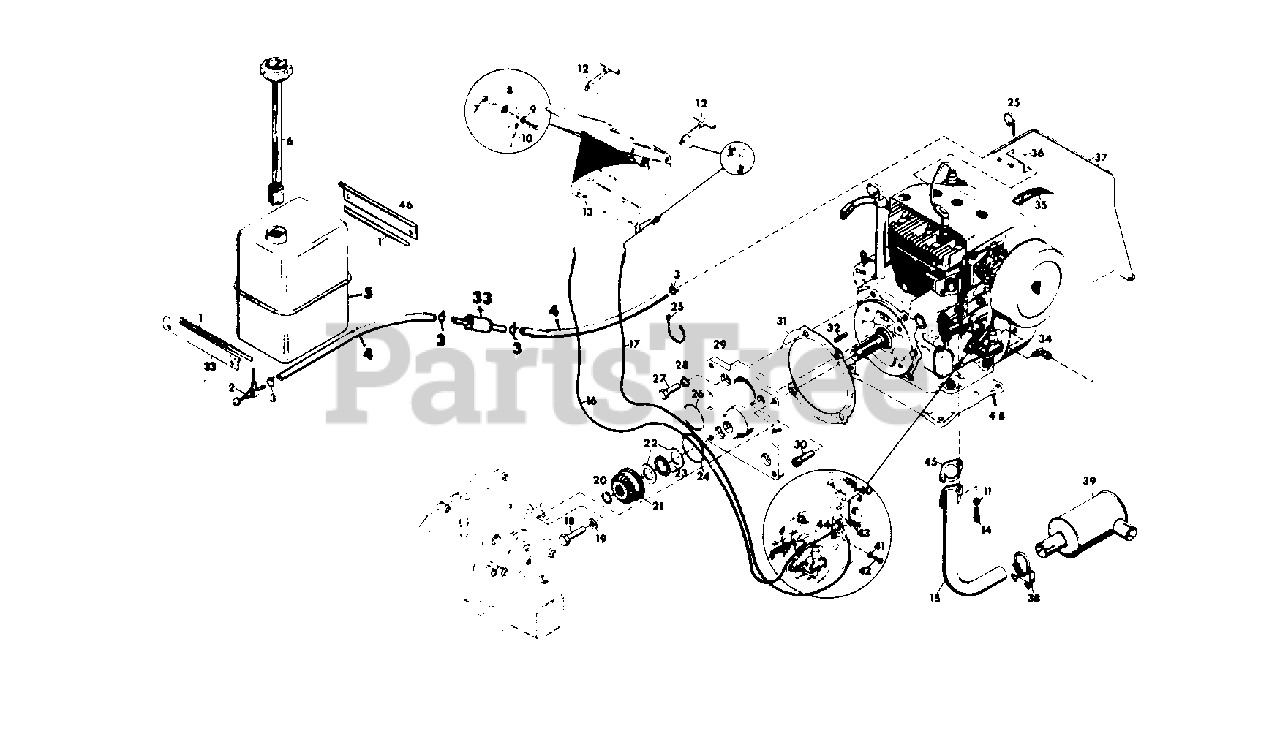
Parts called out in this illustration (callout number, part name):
1	MOULDING
2	VALVE, FUEL; 90 DEG. REVERSE FLOW
3	CLAMP, FUEL HOSE
4	LINE, FUEL
5	TANK, FUEL
6	GAUGE, GAS
7	NUT, LOCK 1/4-28
8	WASHER, FRICTION
9	WASHER, SPRING
10	BOLT, HEX 1/4-28X.75
11	WASHER, LOCK 5/16 SP
12	ASSEMBLY, KNOB AND LEVER
13	PANEL, INSTRUMENT
14	SCREW, CAP 5/16-18X.75 SOCKET HD
15	HEADER, EXHAUST
16	ASSEMBLY, THROTTLE CONDUIT
17	ASSEMBLY, CHOKE CONDUIT
18	BOLT, HEX 1/2-13X1.25
19	WASHER, FLAT .500X1.062X.095
20	RING, RETAINING 1.125 SHAFT
21	GEAR, SPUR AND BEVEL, INPUT
22	RACE, BEARING THRUST 1.127X1.740X/060
23	BEARING, THRUST 1.127X1.740X.078
24	O-RING 3.000X3.188X.094
25	TIE CABLE
26	O-RING 2.500X2.750X.125
27	BOLT, HEX 7/16-14X1.125
28	WASHER, LOCK 7/16 SP HEAVY
29	ADAPTOR, ENGINE
30	SCREW, CAP 7/16-14X1.0 SOCKET HEAD
31	GASKET, ADAPTOR
32	KEY, SQUARE, .250X1.250
33	FUEL FILTER
34	ELBOW, 1/4 BALL SLEEVE ASM.
35	DECAL, AIR CLEANER INSTRUCTION
36	BRACKET, FUEL LINE SUPPORT
37	CONNECTOR TO PUMP FUEL LINE
38	CLAMP, MUFFLER
39	MUFFLER, EXHAUST
40	CLIP, SPEED
41	WASHER, LOCK 1/4 SP
42	SCREW, MACH. 1/4-20X.5 PAN HD
43	NUT, HEX 1/4-20
44	BRACKET
45	GASKET, EXHAUST
46	BRACKET, REAR TANK
47	BRACKET, FORWARD TANK
48	ENGINE, 12 HP 4-WHEEL ELECT. CONS.
